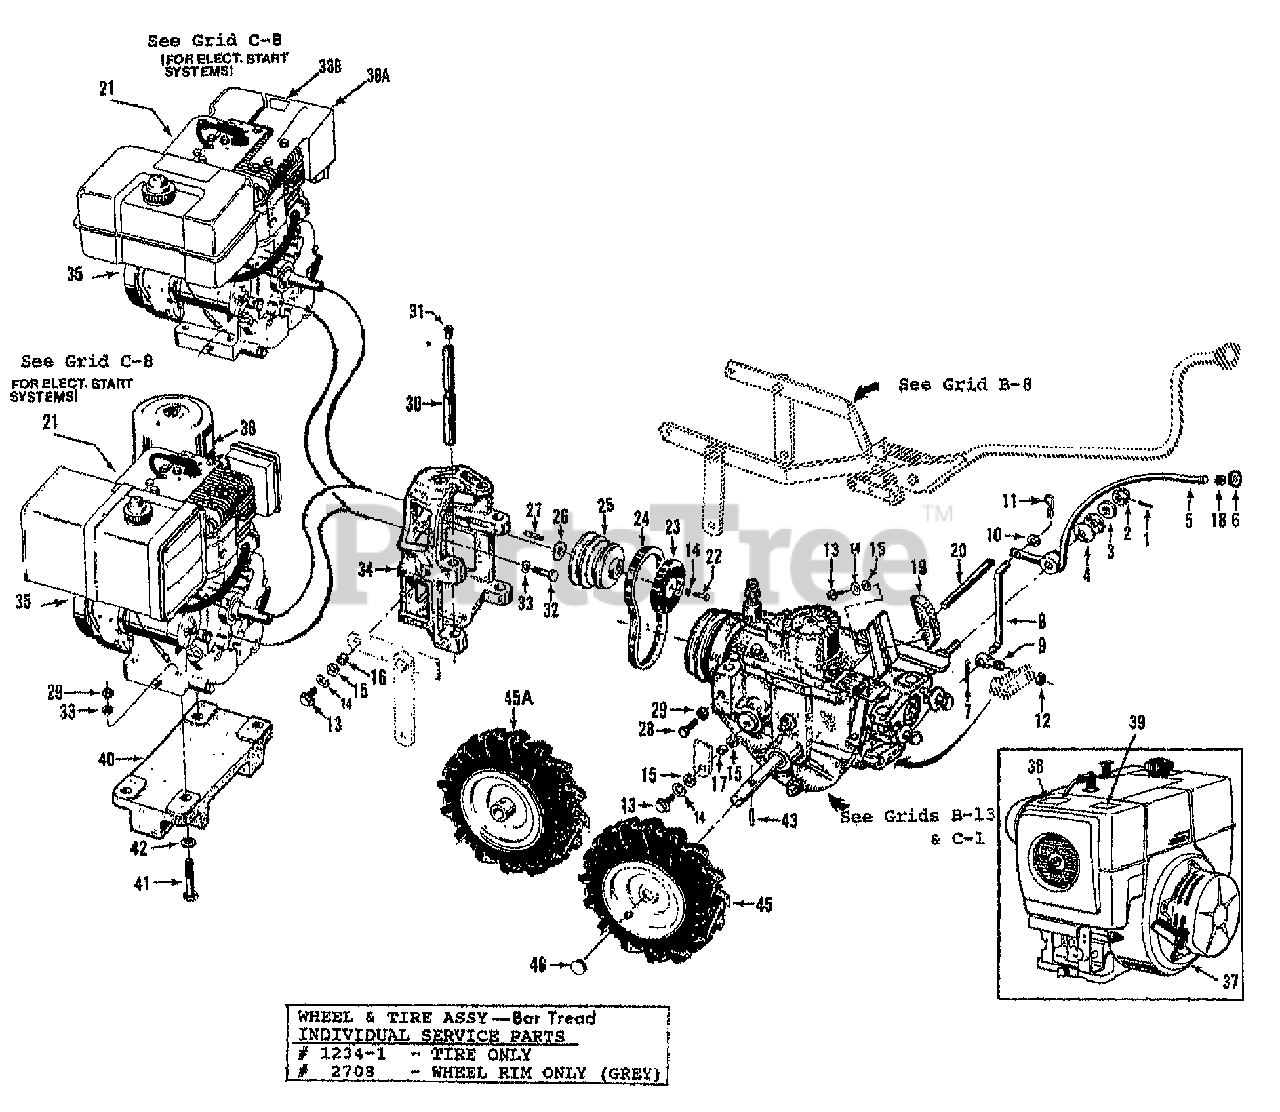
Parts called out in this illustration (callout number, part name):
1	PIN-SPRING .125 X 1
2	NUT-HEX 1/2-20 (SLOTTED)
3	WASHER-# SHOULDER ZP
4	WASHER-# 1.97X1X.118
5	LVR-W/KNOB (WHEEL SPEED) (INCL. 6 & 18)
6	KNOB-WHEEL SPEED HORSE (INCL. 18 & PLASTIC DECAL INLAY)
7	PIN-COTTER .094X1.0
8	ROD-CONNECTING
9	SWIVEL
10	WASHER-FLAT 5/16 SAE
11	PIN-CLIP .08
12	NUT-H/LK 5/16-18
13	SCR-HH 3/8-16X1.0 G5 ZP
14	WASHER-LK .375 @ DEPL
15	WASHER-FLAT 3/8 SAE
16	THIS REF. NO. NOT USED
17	BUSHING-.5X.375X.3
18	RING-TOLERANCE .5325 ID
19	KIT-ADJ BLOCK 4 SP (INCL. 13, 15 & 20)
20	BAR-ADJUST, 7" W/MEASURING GAUGE
21	DECAL-STARTING STABIL, B&S
22	SCR-HH 3/8-24X1.5 G5
23	KIT-ADJ BLOCK/REV DISC (INCL. 19)
23	DISC ONLY - REVERSE, RUBBER RIMMED
24	BELT-FORWARD DRIVE
25	PULLEY-ENG MACH
26	SHIM-1.0X.7656X.062
26	SHIM-1.0X.7656X.031
27	KEY-.188 SQ X 2.33
28	BOLT-HEX HD., 5/16-18x1", GR 5
29	NUT-HEX 5/16-18 ZP
30	BAR-ENG MTG W/CAP PLUG
31	PLUG-CAP (RED)
32	BOLT-HH 5/16-24X1.125 G5 ZP
33	WASHER-LK .312 ZP
34	MOUNT-MOTOR HSE OPC PNT
35	TILLER-7HP STD HORSE
35	TILLER-7HP EL HORSE
35	TLR-HORSE 8HP STD B&S
35	TILLER-8HP EL HORSE B&S
35	OBS-HORSE 7HP STD CA
35	OBS-HORSE 7HP ELC CA
35	TILLER-8 T/B STD HORSE I/P B&S
35	TILLER-8HP T/B EL HORSE B&S I/P
37	TILLER-8HP STD PRO HORSE
37	TILLER-8HP EL PRO HORSE
37	OBS-HORSE 8HP STD CA
37	OBS-HORSE 8HP ELC CA
37	TILLER-7HP T/B STD HORSE
37	TILLER-7HP T/B ELEC HORSE
38	DECAL-HOT SURFACE
38A	GUARD-MUFFLER
38B	DECAL-HOT SURFACE
39	DECAL-STABIL STARTING
40	WEIGHT-ENG ECONO PNT
41	SCR-HH 5/16-18X2.25 G5ZP
42	SPACER-.88X.385X.09 ZP
43	PIN-SPIROL .313 X 1.5
45	ASSM-TIRE&WHEEL LH GRAY
45A	ASSM-TIRE&WHEEL RH GRAY
46	CAP-HUB BLK PLASTIC (REPLACES 9145)
